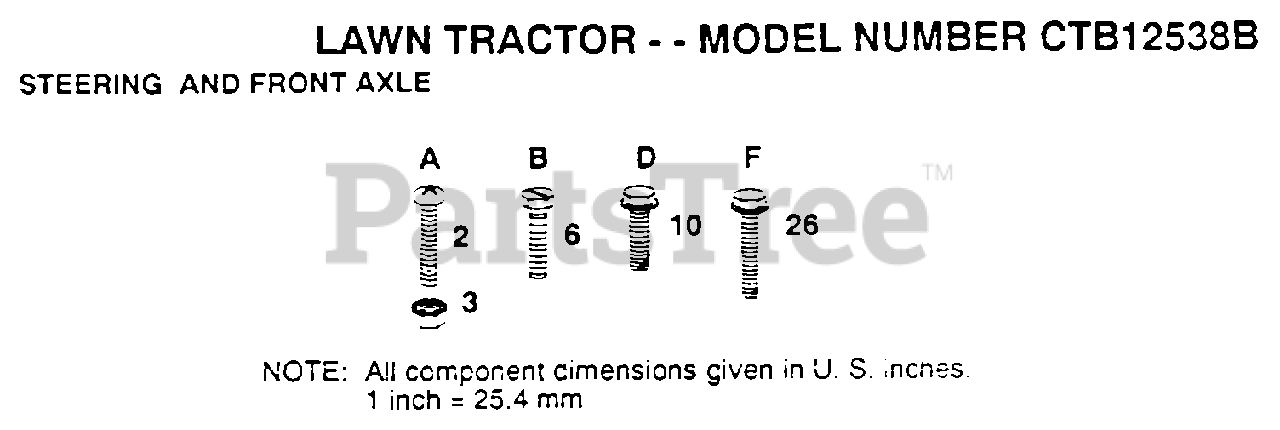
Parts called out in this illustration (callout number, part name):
2	SCREW
6	SCREW LT
10	SCREW LT
26	SCREW
